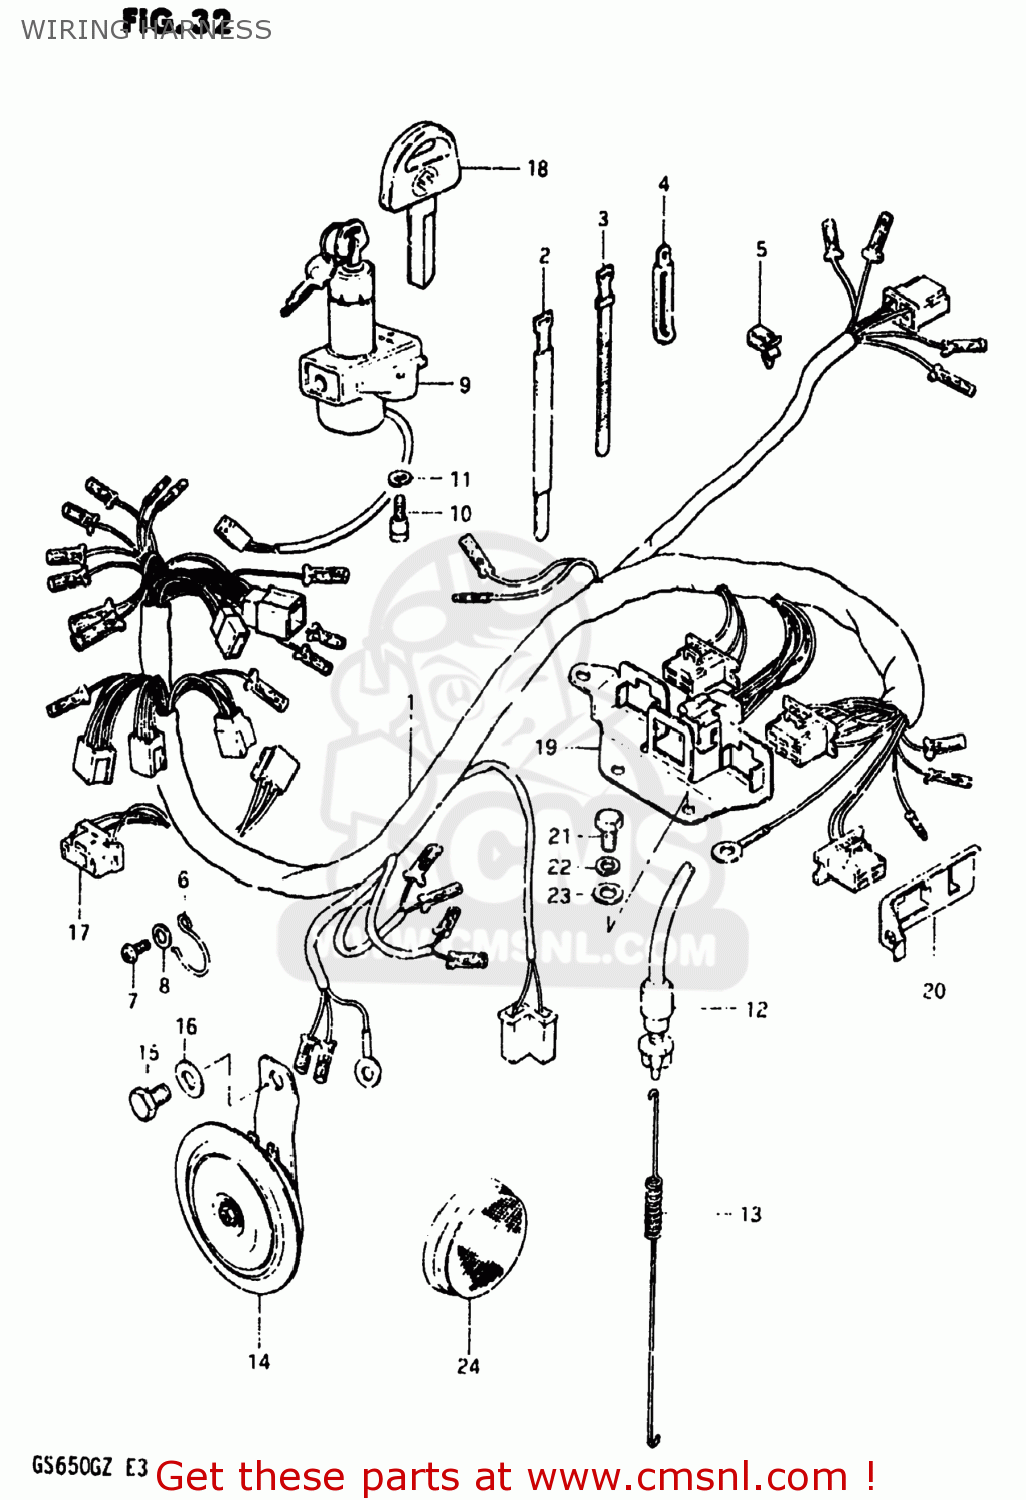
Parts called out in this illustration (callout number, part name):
1	HARNESS,WIRING
2	CLAMP
3	CLAMP
4	CLAMP
5	CLIP
6	GUIDE,WIRING HARNESS
7	SCREW 6X12
8	WASHER
9	LOCK ASSEMBLY,STEERING
10	BOLT
11	LOCK WASHER
12	SWITCH ASSEMBLY,STOP LAMP
13	SPRING
14	HORN ASSEMBLY
15	BOLT 8X12
16	WASHER
17	LEAD WIRE,HEADLAMP
18	KEY,BLANK
19	PLATE, COUPLER HOLDER (A)
20	PLATE, COUPLER HOLDER (B)
21	BOLT
22	LOCK WASHER
23	WASHER
24	REFLEX REFLECTOR,RR
